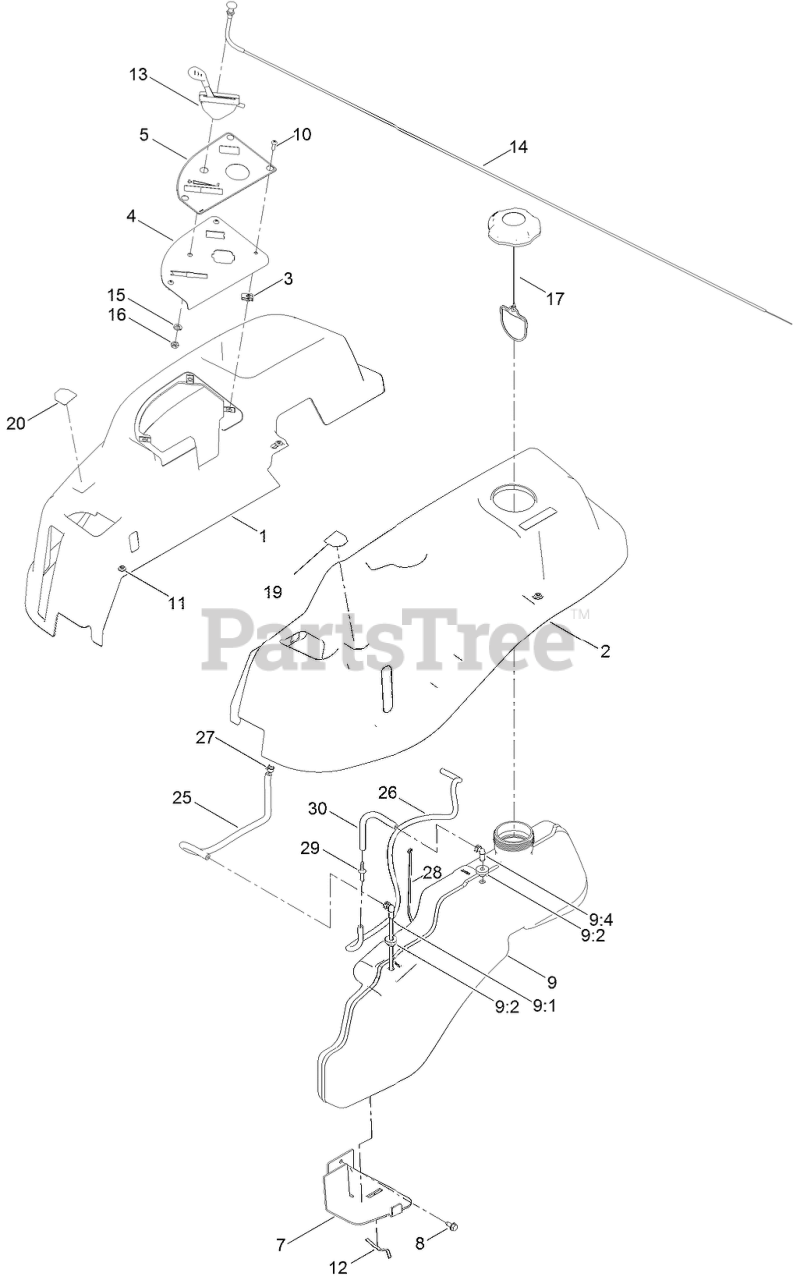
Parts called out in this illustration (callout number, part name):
1	POD-RH
2	POD-LH
4	PLATE-CONTROL
5	DECAL-PANEL, CONTROL
7	SUPPORT-TANK, FRONT
8	SCREW-HWHTF
9	FUEL TANK ASM
9:1	CONNECTOR-ELBOW, 90 DEG
9:2	BUSHING
9:4	FITTING-PLASTIC
10	SCREW-PRH
11	SCREW-SHOULDER
12	SPRING
13	CABLE-THROTTLE
14	CABLE-CHOKE
15	WASHER-LOCK
16	NUT-HJ
19	DECAL-LEVER, CONTROL (LH)
20	DECAL-LEVER, CONTROL (RH)
25	HOSE-FUEL
26	HOSE-FUEL
27	CLAMP-HOSE
28	TIE-CABLE
29	ADAPTOR-ORIFICE
30	HOSE-FUEL
